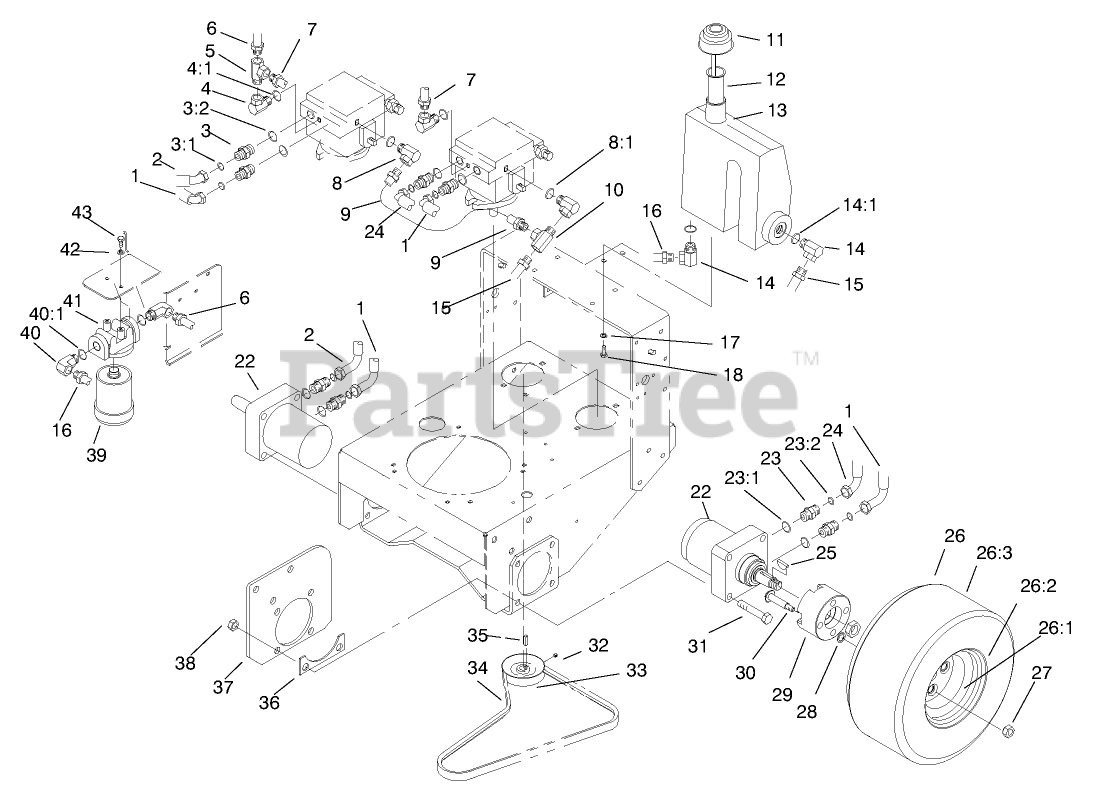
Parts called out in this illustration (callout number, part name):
1	HYDRAULIC HOSE ASM
2	HYDRAULIC HOSE ASM
3	FITTING-STRAIGHT
3:1	O-RING
3:2	O-RING
4	SWIVEL-PIPE, FEMALE
5	FITTING-HYD, TEE
6	HYDRAULIC HOSE ASM
7	HYD HOSE ASM
8	FITTING-HYD, 90 DEG
8:1	O-RING
9	HYD HOSE ASM
10	FITTING-HYD, TEE
11	OIL CAP ASM
12	SCREEN-FILLER
13	RESERVOIR-OIL
14	FITTING-HYD, 90 DEG
15	HYDRAULIC HOSE ASM
16	HYD HOSE ASM
17	WASHER-LOCK
18	SCREW-HH
22	WHEEL MOTOR ASM
23	FITTING-STRAIGHT
23:1	O-RING
23:2	O-RING
24	HYDRAULIC HOSE ASM
25	KEY-WOODRUFF
26	ASM-Wheel & Tire
26:1	STEM-VALVE
26:2	WHEEL
27	NUT-LUG
28	PUSHNUT
29	HUB-WHEEL
30	SCREW-HH
31	SCREW-HH
32	SCREW-SET
33	PULLEY-PUMP
34	BELT-V
35	KEY-PUMP
36	SPACER-FRAME
37	PLATE-FRAME
38	NUT-LOCK, NI
39	CARTRIDGE-FILTER, OIL
40	FITTING-HYD, 90 DEG
40:1	O-RING
41	HEAD-FILTER
42	WASHER-LOCK
43	SCREW-HH
